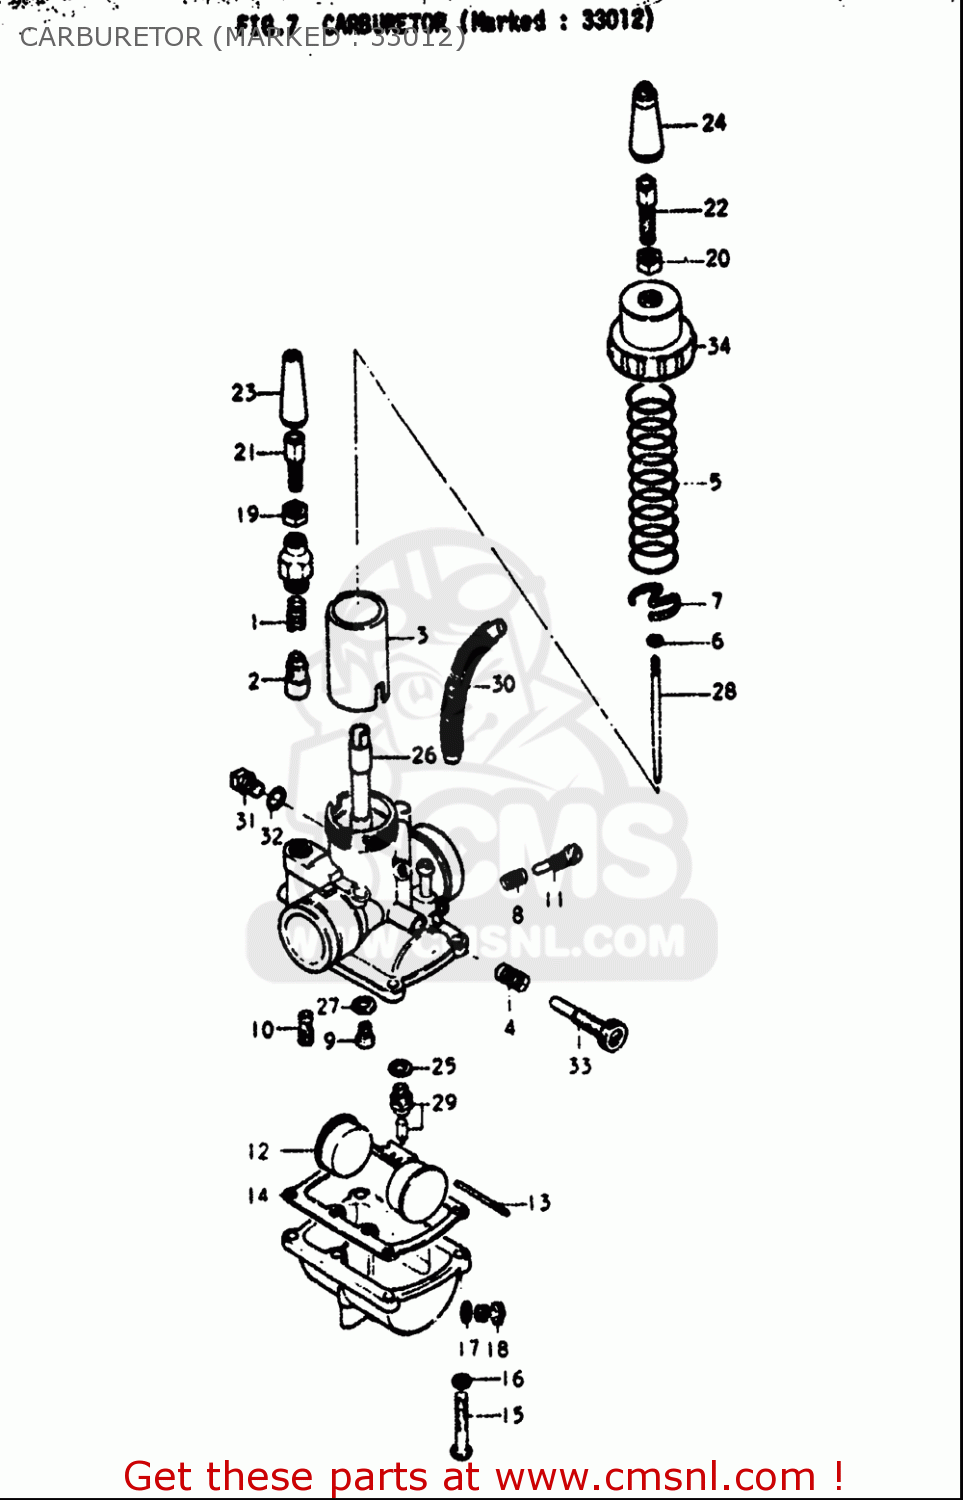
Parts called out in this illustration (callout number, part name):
1	SPRING
2	PLUNGER,STARTER
4	SPRING
6	CLIP
7	SEAT,THROTTLE VALVE SPRING
8	SPRING
9	JET,MAIN
10	JET,PILOT(22.5)
11	SCREW,PILOT AIR
12	FLOAT
13	PIN,FLOAT
14	GASKET,FLOAT CHAMBER (NAS)
15	SCREW 4X16
16	WASHER,LOCK
17	GASKET,DRAIN,PLUG (NAS)
18	PLUG
19	NUT
21	ADJUSTER,CABLE
23	CAP
25	GASKET,VALVE SEAT (NAS)
27	WASHER
28	NEEDLE,JET
29	VALVE ASSY,NEEDLE
31	BOLT
32	GASKET,THRO VALVE INSPECTION (NAS)
